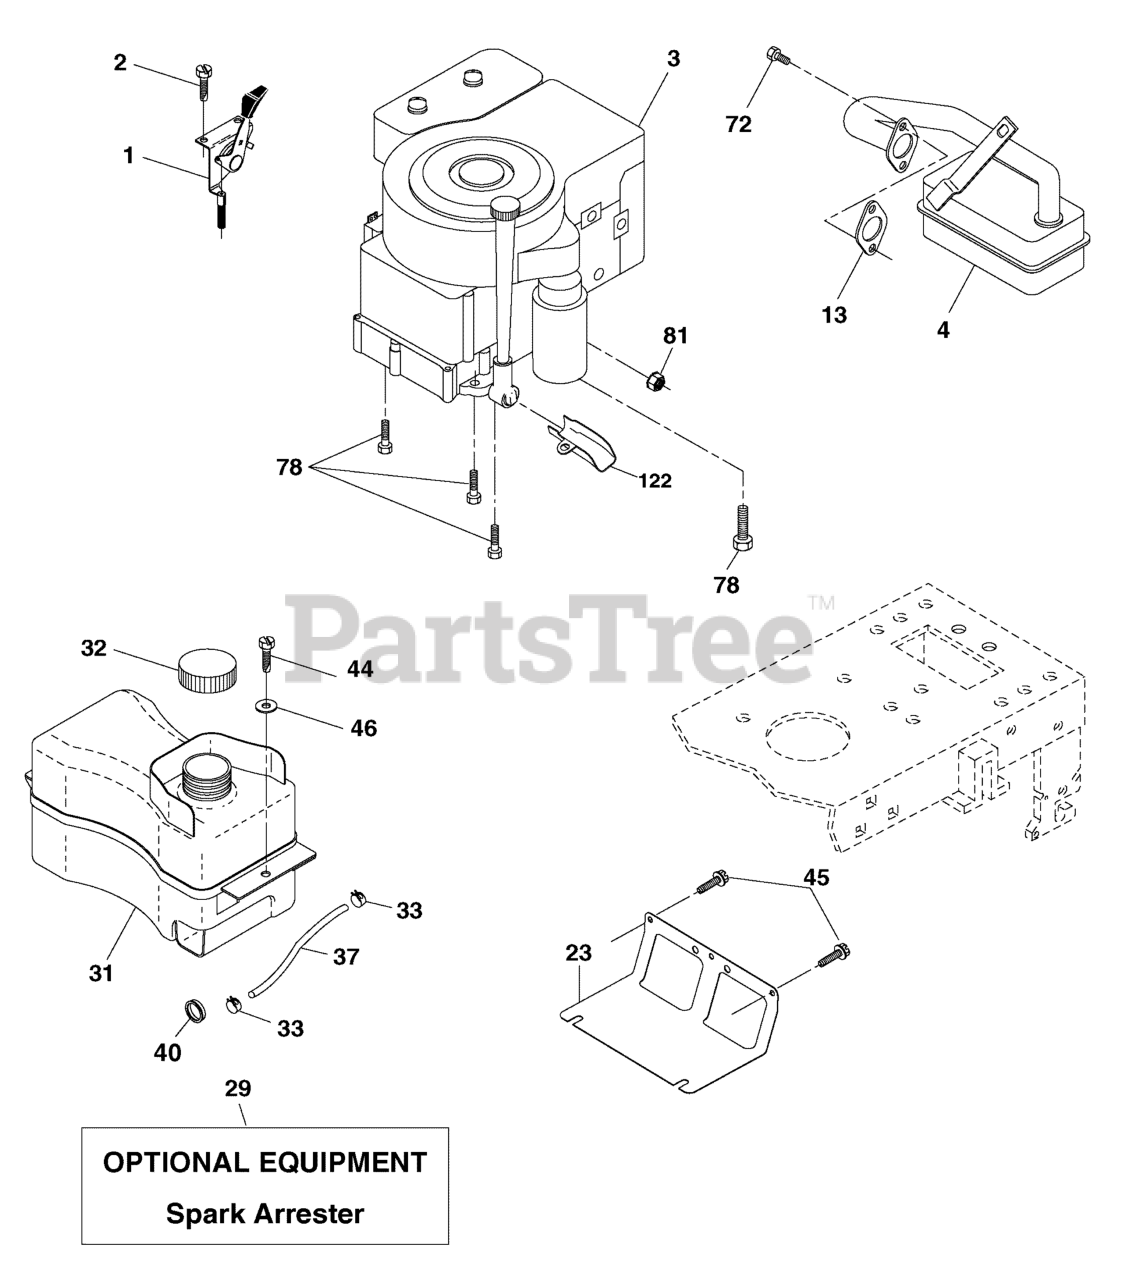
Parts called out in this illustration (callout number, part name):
1	CONTROL Th/Ch
2	SCREW, Hex Thd Cut 1/4-20 x 1/2
3	* Engine, Briggs & Stratton
4	MUFFLER, Exhaust B&S
13	GASKET. Eng 1 313 Id Tin Plated
23	SHIELD, BRN/DBR Guard
29	KIT, Spark Arrestor (Flat Scrn)
31	TANK, Fuel Front
32	CAP, Fuel
33	CLAMP, Hose
37	FUEL LINE, 20"
40	BUSHING, Snap Nyl Blk Fuel Line
44	SCREW, Thdrol 1/4-20 x 3/4
45	SCREW, Hex Wsh Thdrol 3/8-16
46	WASHER, 9/32 x 7/8 x 16 Ga.
72	SCREW, Socket Hd 5/16-18 x .75
78	SCREW, 3/8-16 x 1-1/4
81	NUT, Keps Hex 1/4-20 unc
122	EXTENSION, Drain Oil
